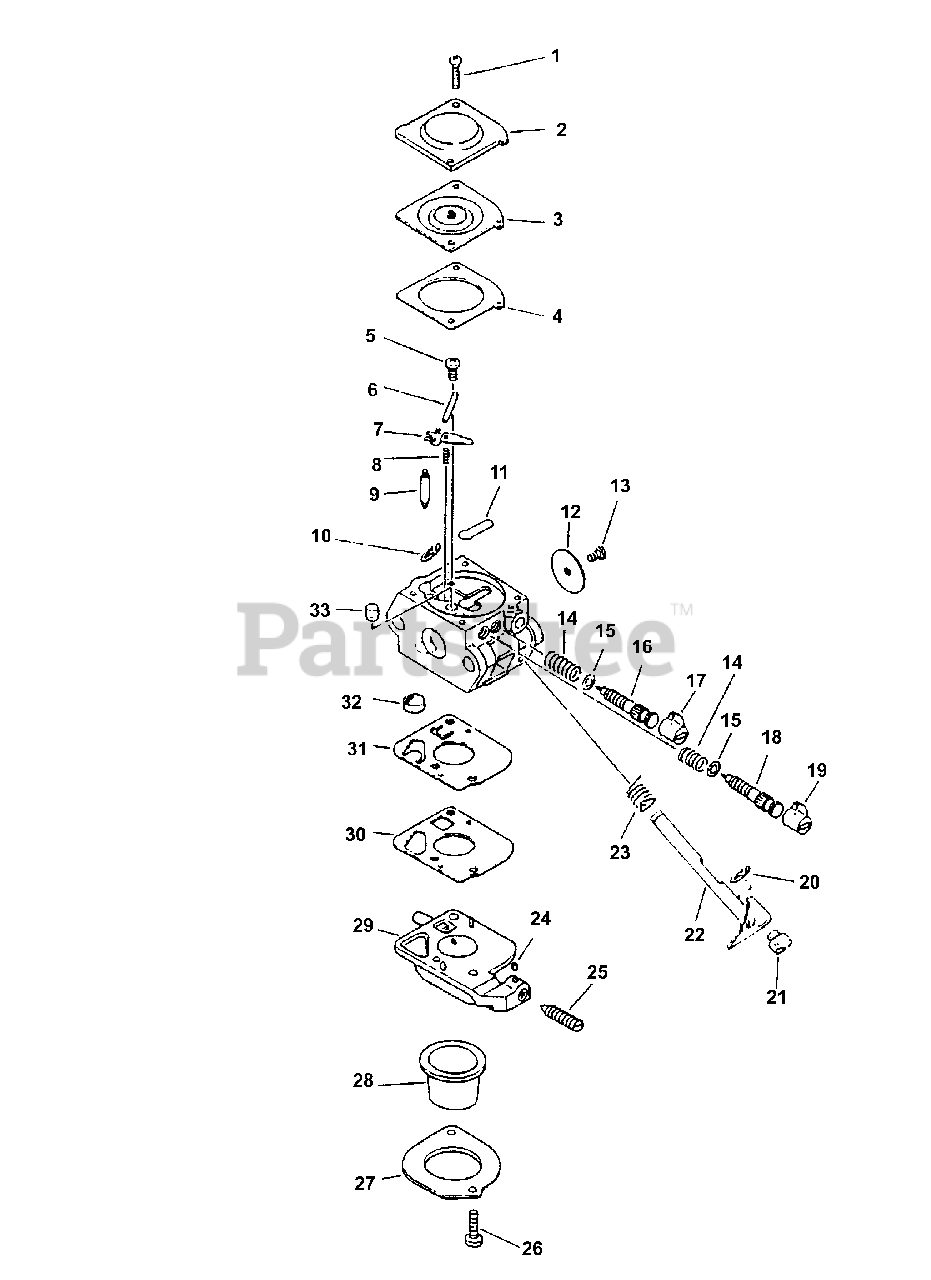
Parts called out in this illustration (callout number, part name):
2	COVER, METERING
3	DIAPHRAGM, METERING
4	GASKET, METERING
5	SCREW, METERING LEVER PIN
6	PIN, METERING LEVER
7	LEVER, METERING
8	SPRING, METERING LEVER
9	VALVE, INLET NEEDLE
10	RING, RETAINING
11	PLUG, WELCH
12	VALVE, THROTTLE
16	NEEDLE - LOW SPEED
17	CAP, LIMITER
18	NEEDLE - HIGH SPEED
19	CAP, LIMITER
20	RING, RETAINING
22	SHAFT, THROTTLE
23	SPRING, RETURN
24	PIECE, FRICTION
25	SCREW, IDLE ADJUST
26	SCREW, RETAINER
27	RETAINER, PURGE BULB
28	BULB, PURGE
29	BASE, PURGE
30	GASKET, PURGE
31	DIAPHRAGM, PURGE
32	STRAINER
33	NOZZLE, CHECK VALVE
A	REPAIR KIT
B	DIAPHRAGM/GASKET KIT
